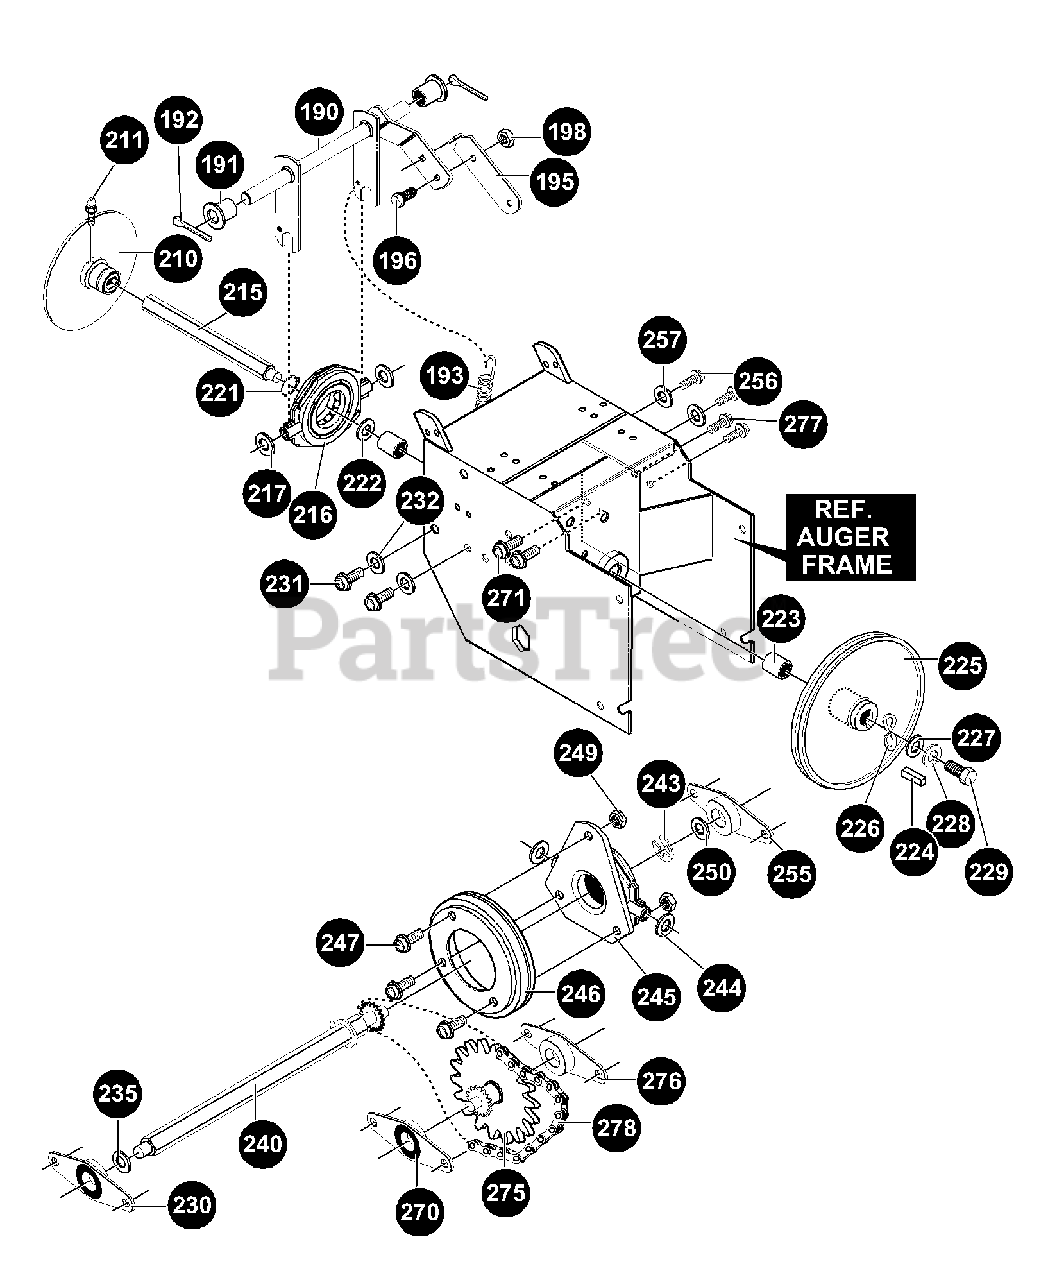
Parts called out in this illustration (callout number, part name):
190	LEVER, ASSY TRACTION
191	BEARING, FLANGE
192	PIN, COTTER
193	SPRING, RETURN
195	LEVER, SPRING
196	SCREW, 1/4-20X .63
198	NUT, 1/4-20
210	DISC, ASSY
211	ZERK, GREASE
215	SHAFT, HEX TRACTION
216	BEARING, TRUNION
217	FLATWASHER,.53 X1.00X.063
221	RING, RETEX
222	FLATWASHER .680X1.12X.060
223	BEARING, BALL
224	KEY, SQUARE
225	PULLEY, V3L 6.50X .56
226	WASHER, WAVE
227	FLATWASHER .281X1.00X.063
228	WASHER, .263X.49X.07
229	SCREW, 1/4-20X .75 HHC
230	BEARING & RETAINER
231	SCREW, 5/16-18X .50
232	WASHER,.328X.60X.09
235	WASHER,.502X .75X.0605
240	HEX, ASSY#40-8T
243	RING, RETEX
244	FLATWASHER, .53 X1.00X.063
245	BEARING, TRUNION
246	WHEEL, ASSY FRICTION
247	SCREW, 1/4-20X .63
249	NUT, 1/4-20 HEX KEPS
250	WASHER,.502X .75X.0605
255	BEARING & RETAINER
256	SCREW, 5/16-18X .50
257	WASHER, .328X.60X.09
270	BEARING & RETAINER
271	SCREW, 5/16-18X .50
275	JACK, ASSY#41-36T&7T
276	BEARING & RETAINER
277	SCREW, 5/16-18X .50
278	CHAIN, ROLLER #42 X 40P
